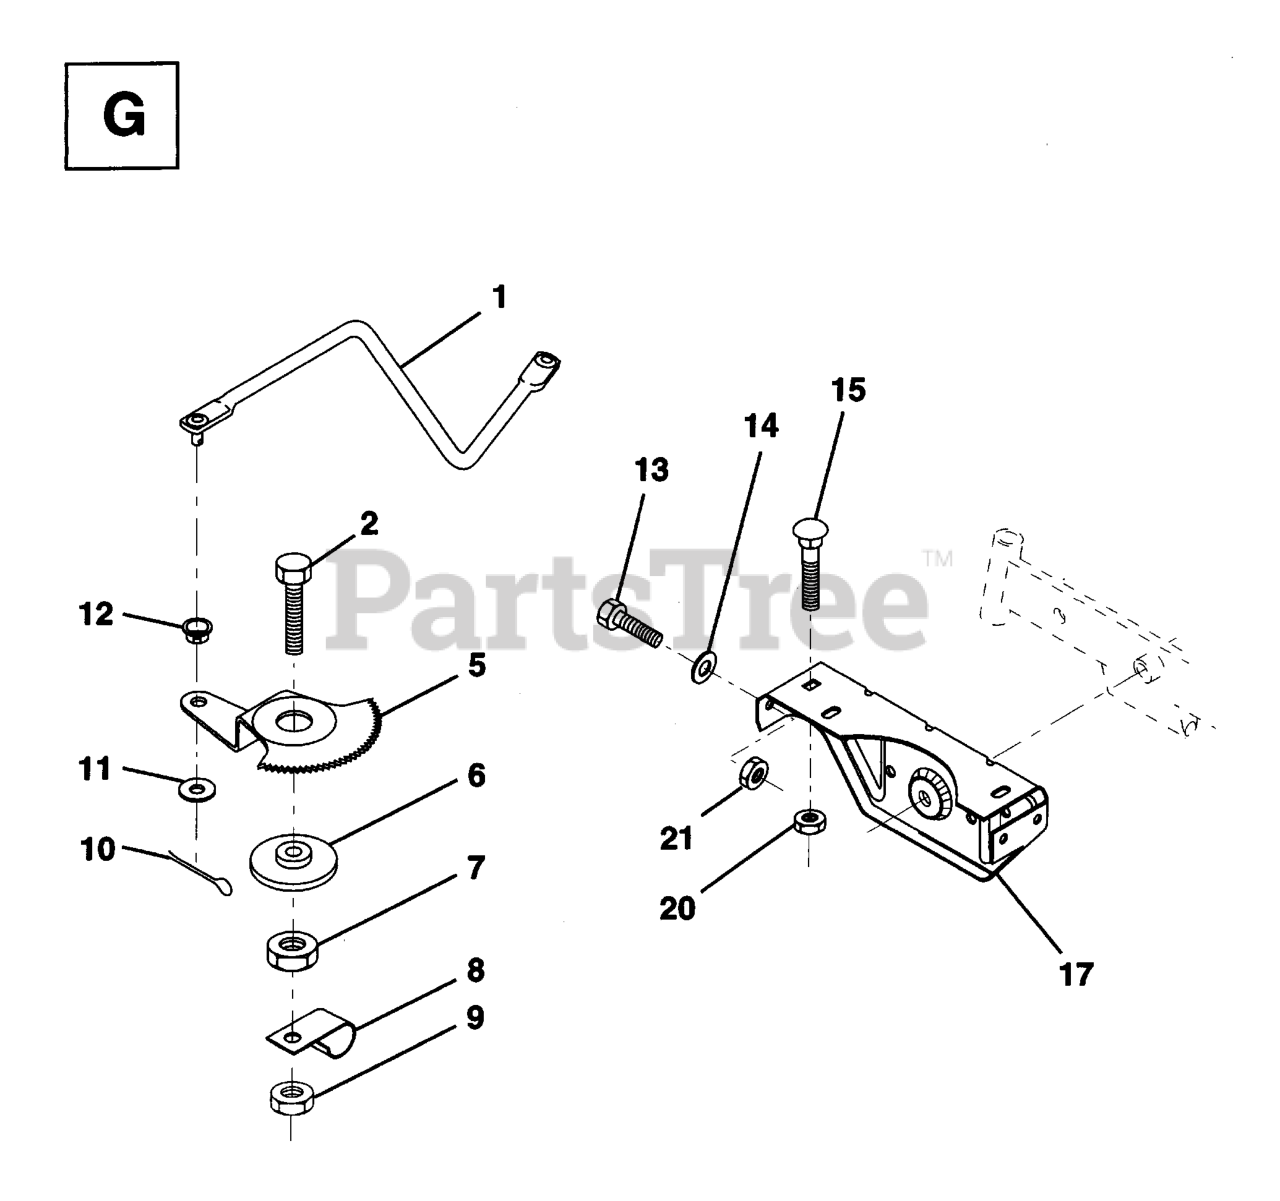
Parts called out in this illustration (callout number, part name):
5	GEAR SECTOR
7	NUT
8	CLIP INSULATOR
9	NUT LTV
10	COTTER PIN
11	WASHER
12	BUSHING.DRAGLINK (2 2)
13	BOLT
14	WASHER
17	SUPPORT/AXLE FRONT
20	NUT
21	NUT.71038.31-18.HEX.NYLOCK
